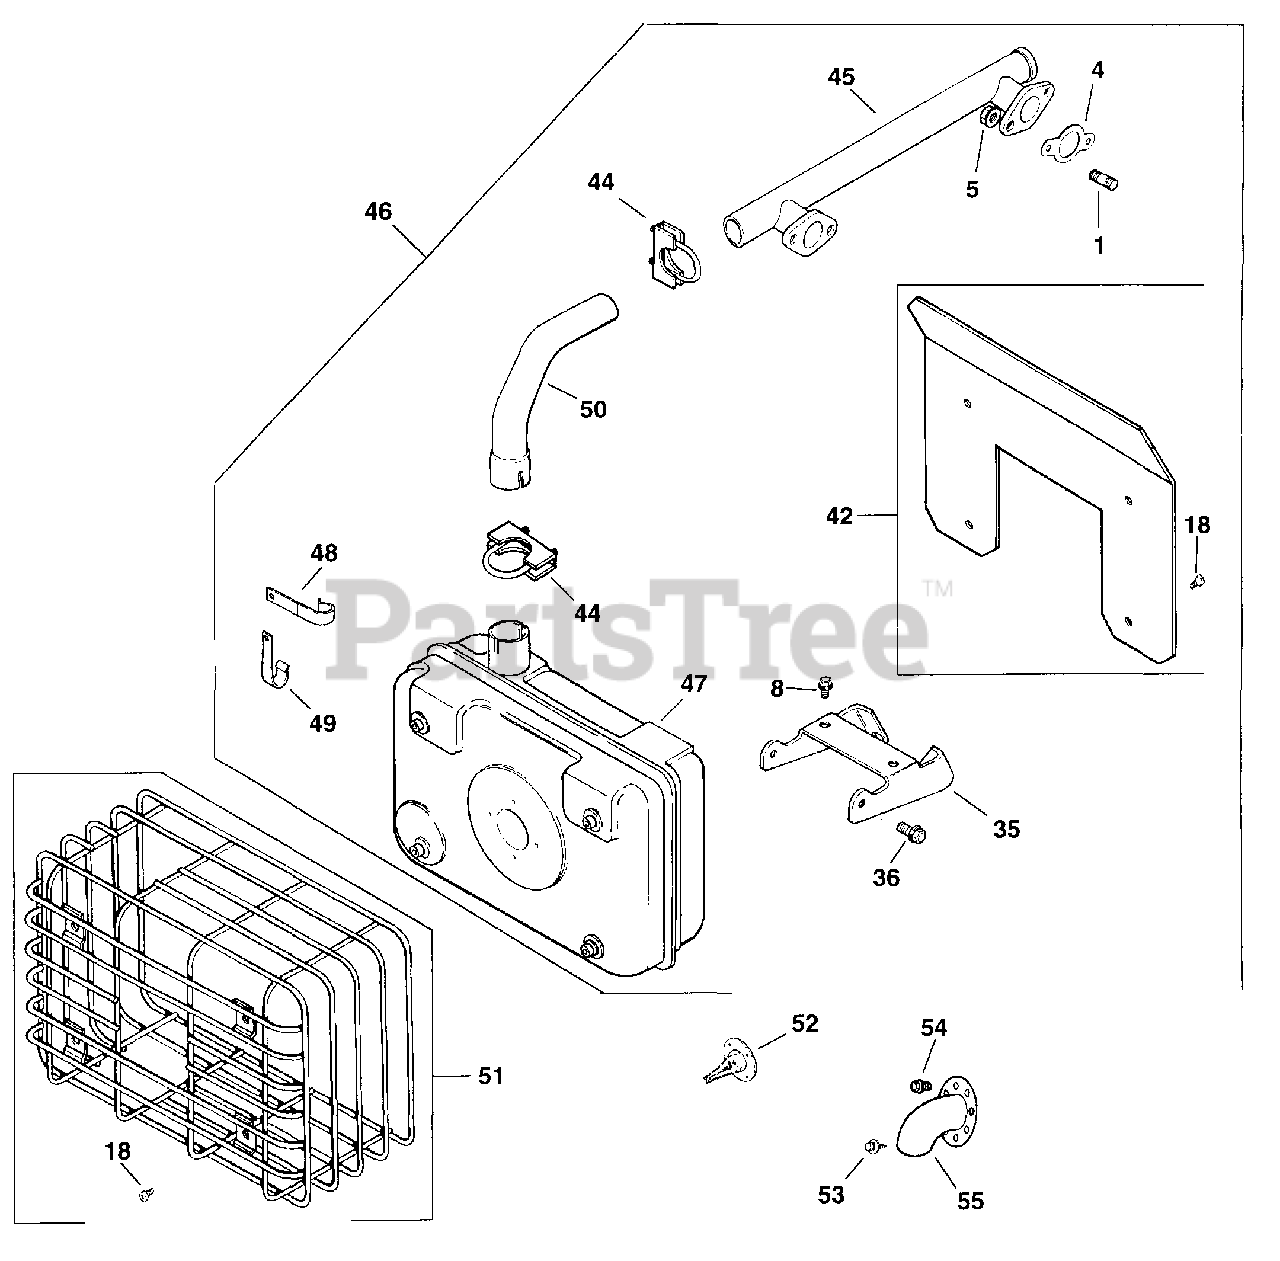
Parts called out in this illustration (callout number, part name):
1	STUD - USE M-829033
5	NUT - USE M-841080
8	Screw, hex. flange M8x1.25x20
18	SCREW - USE M-555010
35	BRACKET, MUFFLER
36	SCREW - USE M-645016
42	KIT, HEAT SHIELD
44	CLAMP, MUFFLER
45	MANIFOLD, EXHAUST
46	KIT, MUFF. MT.-OIL FILT
47	MUFFLER, SIDE MOUNT - USE 24 068 153-S
48	CLIP, CABLE - USE 24 154 10-S
49	CLIP, CABLE
50	PIPE, EXHAUST
